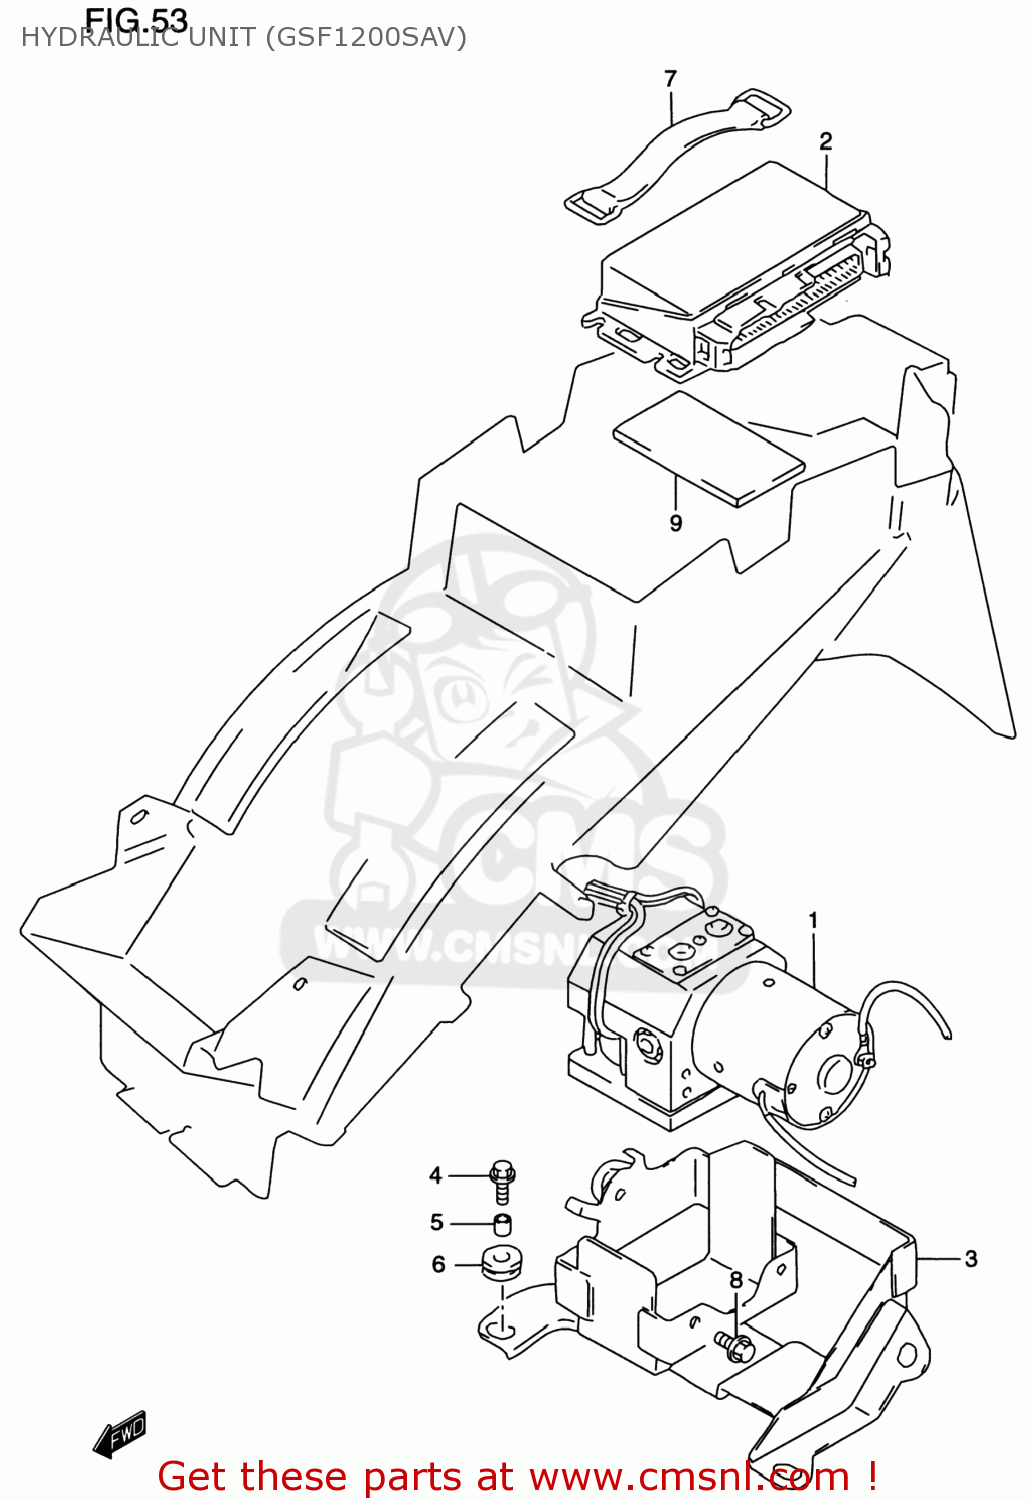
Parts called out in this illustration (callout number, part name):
1	UNIT ASSY,HYDRAULIC ABS
2	ECU ASSY,ABS
3	HOLDER,HYDRAULIC UNIT
4	BOLT(6X20)
5	SPACER(6.5X9X7)
6	CUSHION
7	BAND
8	BOLT
9	PROTECTOR,BATTERY(70X100X6)
